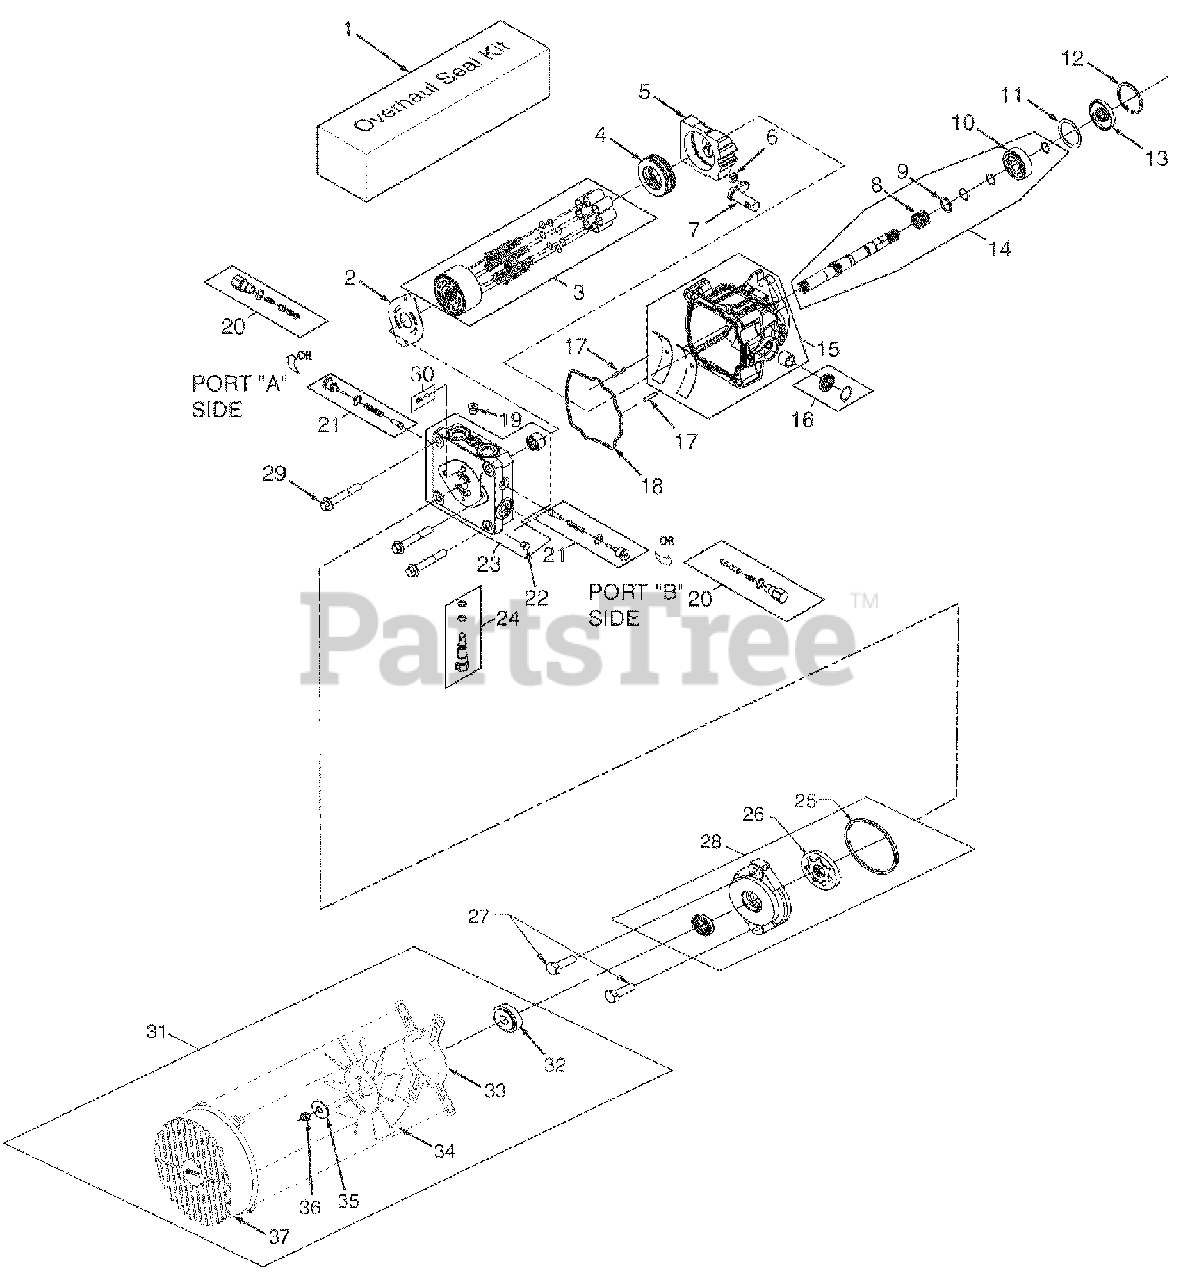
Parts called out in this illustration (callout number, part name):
1	Overhaul Seal Kit
2	Valve Plate
3	Cylinder Block Kit - 16cc
4	Thrust Ball Bearing Assembly
5	Variable Swashplate
6	Slot Guide
7	Trunnion Arm
8	Block Spring
9	Block Thrust Washer
10	Shaft Ball Bearing
12	Retaining Ring
14	Kit, Pump Shaft
15	Housing Kit
16	Trunnion Seal Kit
18	O-Ring
19	Straight Thread Plug
20	Shock Valve Kit
21	Shock Valve Kit
22	Straight Thread Plug
23	End Cap Kit
24	Bypass Valve Kit
26	Gerotor Assembly
27	Socket Head Cap Screw
28	Charge Pump Kit
29	Hex Screw, Flanged Head
30	Charge Relief Kit
31	Fan Kit
33	Bracket, Shroud
35	Washer
37	Shroud
